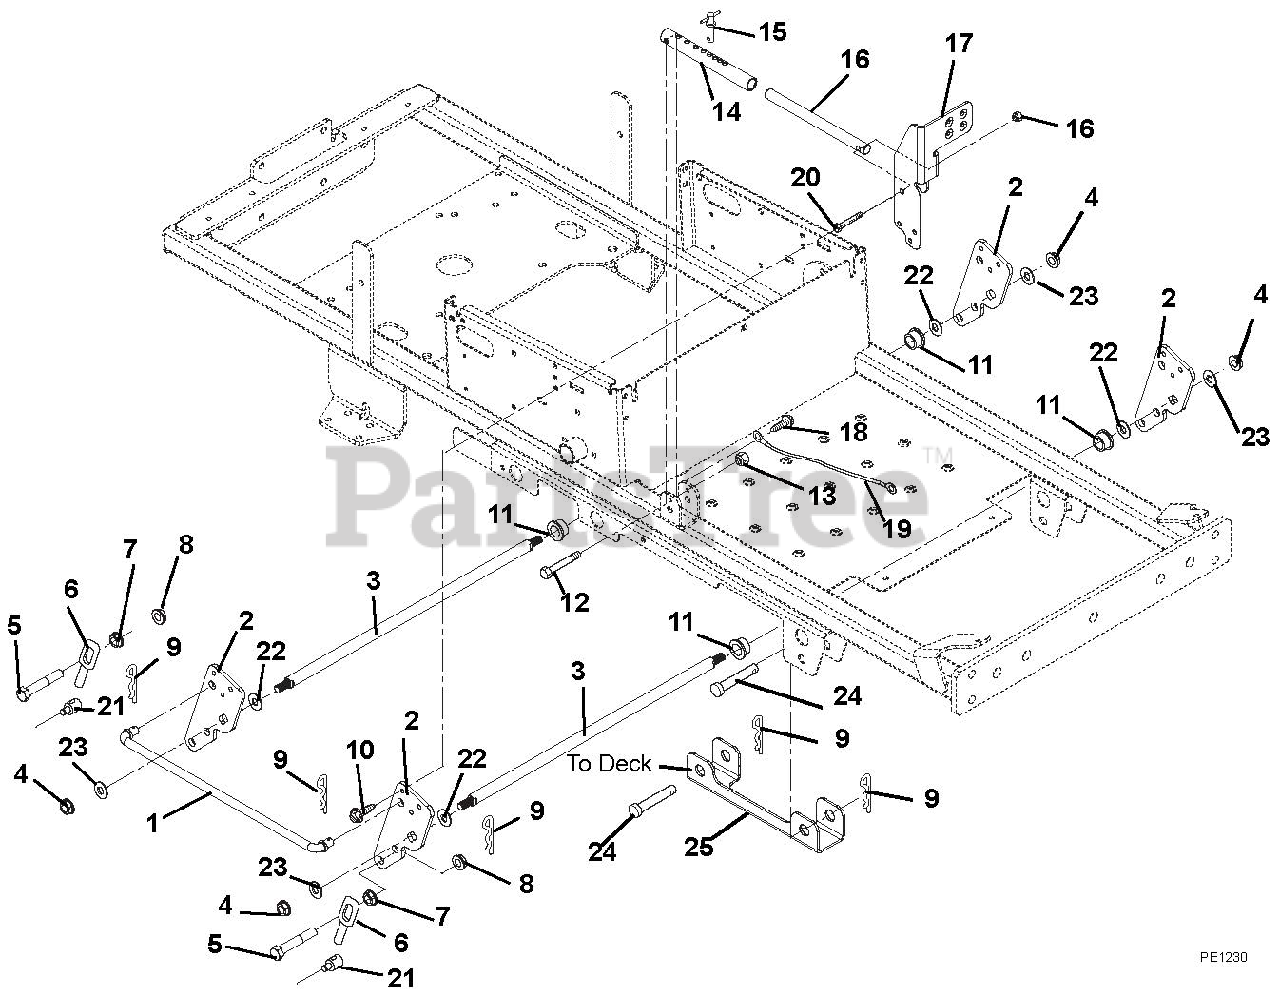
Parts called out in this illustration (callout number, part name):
1	ROD,LIFT
2	LIFT ARM
3	SHAFT, LIFT
4	NUT-HEX .250-28 YWZC
5	BLT-HEX .50-13X2.75 YZ GR8
6	DECK LINK
7	NUT-SPNLK-FLG .50-13 YWZC
8	@NUT-LK-NYL-FLG .50-13 YWZC
9	PIN, HAIR, EXT - #16 YWZC
10	@SCR-TAP .31-18X.50 HWH TR YWZ
11	BSHG-FLG .750X1.000X.625X1.250
12	@BLT-HEX .38-16X2.00 GR5 YWZC
13	@NUT-LK-NYL-FLG .38-16 YWZC
14	TUBE,LIFT STOP
15	PIN, SPRING BALL .375OD X 1.50
16	ROD,LIFT
17	PEDAL,FOOT LIFT
18	@SCR-TAP .25-20X.50 HWH TR YWZ
19	CBL,HOOD
20	@BLT-HEX .38-16X2.50 GR5 YWZC
21	TRUNNION-.50
22	WSHR-FL-STL.755X1.375X.062YWZC
23	WSHR-FL-STL .515X1.625X.250 YZ
24	PIN-CLEV .494X2.50 BRIGHT ZINC
25	CHAANEL, DECK LIFT
